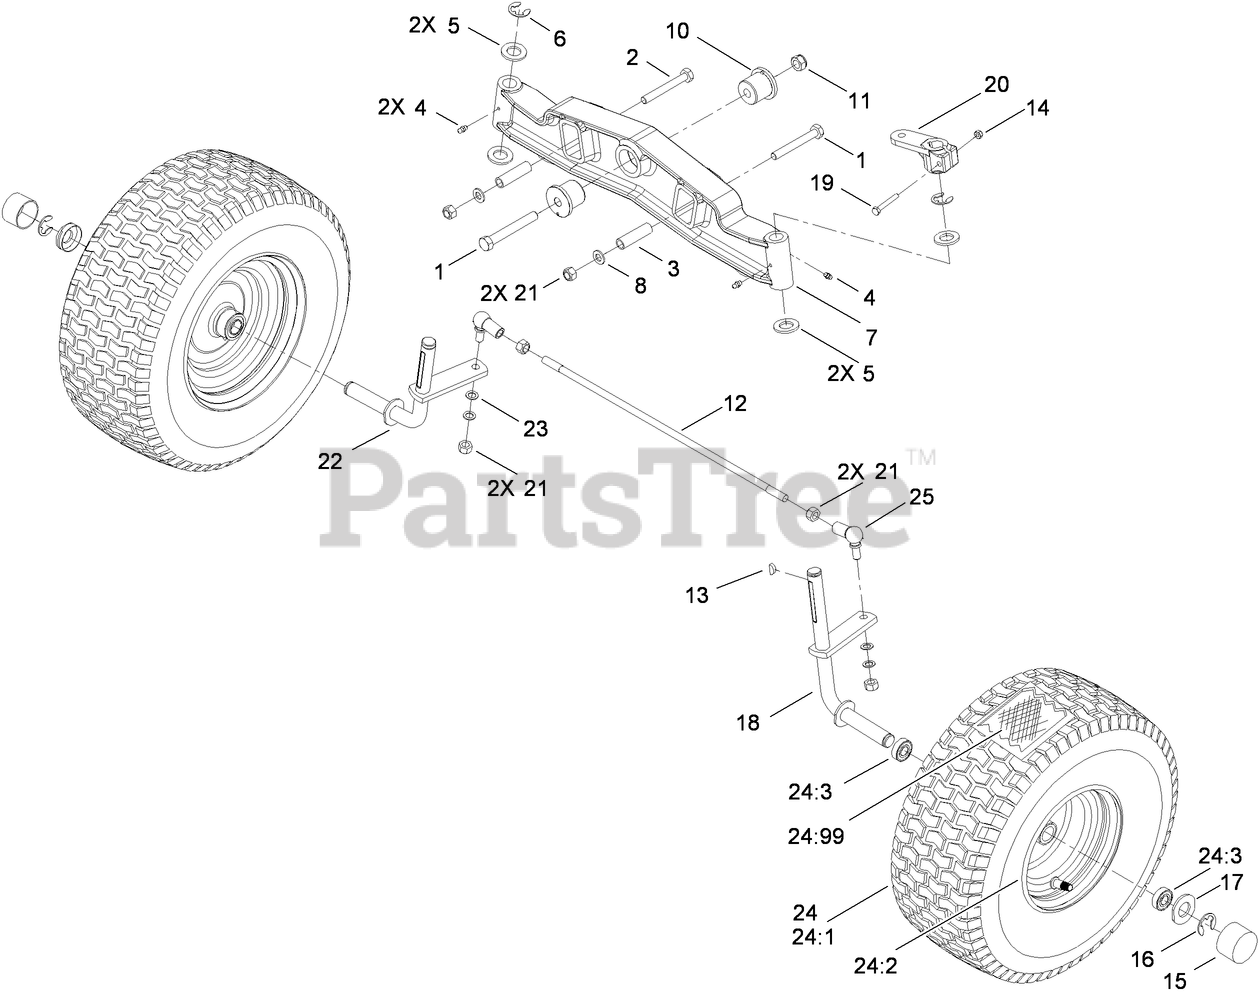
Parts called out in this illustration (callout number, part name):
1	SCREW-HH
2	SCREW-HH
3	SPACER
4	FITTING-GREASE
5	WASHER-FLAT
6	CLIP-SPRING
7	AXLE-FRONT
8	WASHER-FLAT
10	BUSHING-AXLE, FRONT
11	NUT-LOCKING, SELF
12	ROD-TIE, FRONT AXLE
13	KEY-WOODRUFF
14	NUT-LOCK
15	CAP-HUB
16	CLIP-SPRING
17	RETAINER-CAP, HUB
18	SPINDLE-FRONT, LEFT
19	SCREW-HH
20	LEVER-SPINDLE, STEERING
21	NUT-LOCK, NI
22	SPINDLE-FRONT, RIGHT
23	Washer
24	Loose Parts Package
24:2	RIM-FRONT
24:3	BEARING-WHEEL
24:99	TUBE-INNER
25	JOINT-BALL, ANGLE
